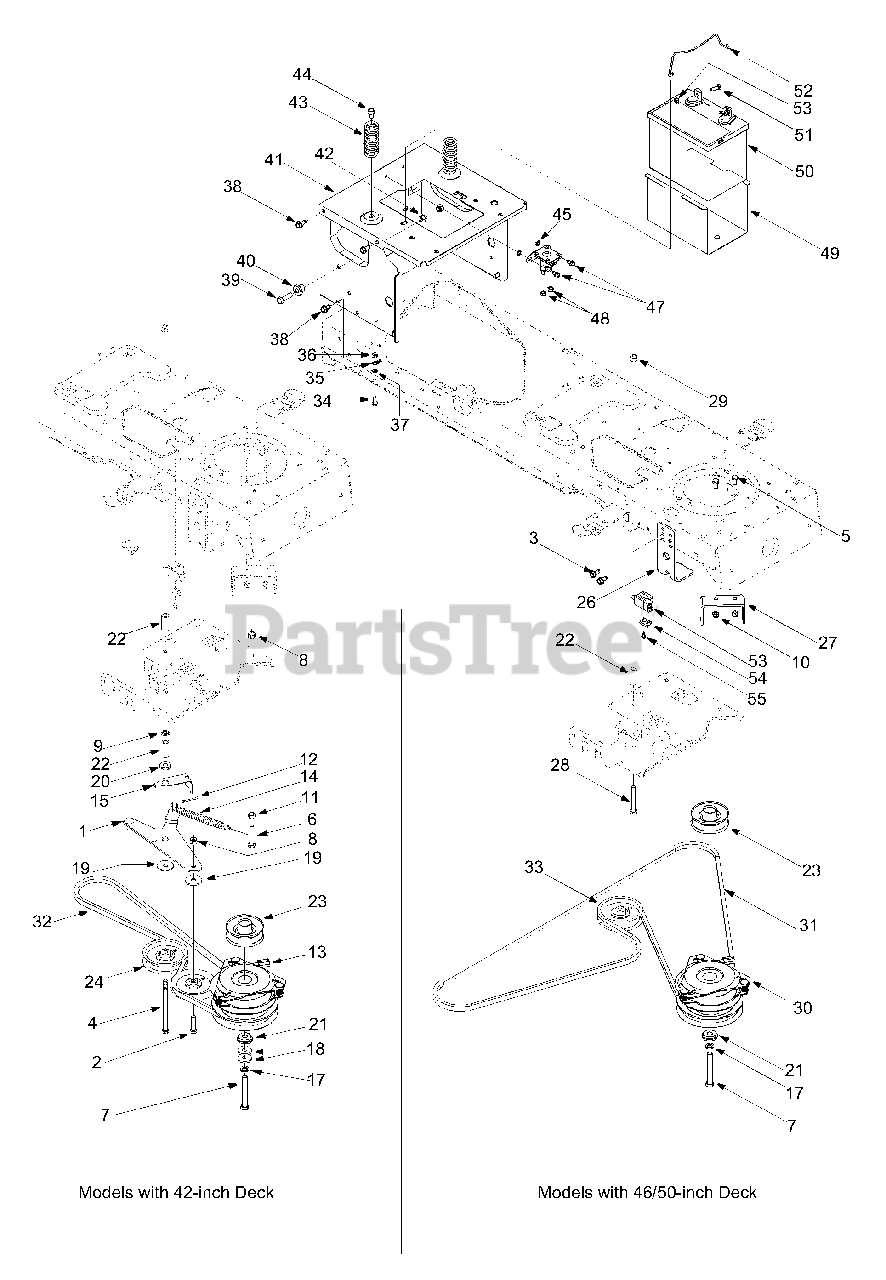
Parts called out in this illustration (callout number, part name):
3	AB Screw 5/16-12 x 0.75
4	Hex Bolt 3/8-16 x 5.5
5	Hex Bolt 5/16-18 x 0.625
6	Hex Bolt 3/8-16 x 2.0
7	Hex Bolt 7/16-20 x 3.25
8	Lock Nut 3/8-16
9	Push Nut
10	Hex Lock Nut 5/16-18
11	Hex Nut 3/8-16
12	Cotter Pin
13	PTO Clutch
14	Extension Spring
15	Belt Guard
16	Flat Washer
17	Lock Washer
18	Flat Washer
19	Flat Washer
20	Shoulder Spacer
21	Shoulder Spacer
22	Spacer
23	Engine Pulley
24	Idler Pulley
25	Idler Pulley
29	Lock Nut
30	PTO Clutch
31	V Belt 46"/50" Deck
32	V Belt 42" Deck
33	Pulley
34	TT Screw 1/4-20 x 0.75
35	Ground Wire
36	Hex Lock Nut 1/4-20
37	Shoulder Screw 3/8-16
38	AB Screw 5/16-12
39	Hex Bolt 3/8-16 x 1.25
40	Shoulder Spacer
43	Compression Spring
44	AB Screw 5/16-12 x 0.75
45	Lock Washer
47	TT Screw 1/4-20 x 0.5
48	Lock Nut 1/4-20
51	Carriage Screw
52	Battery Hold-Down rod
53	Sems Nut
